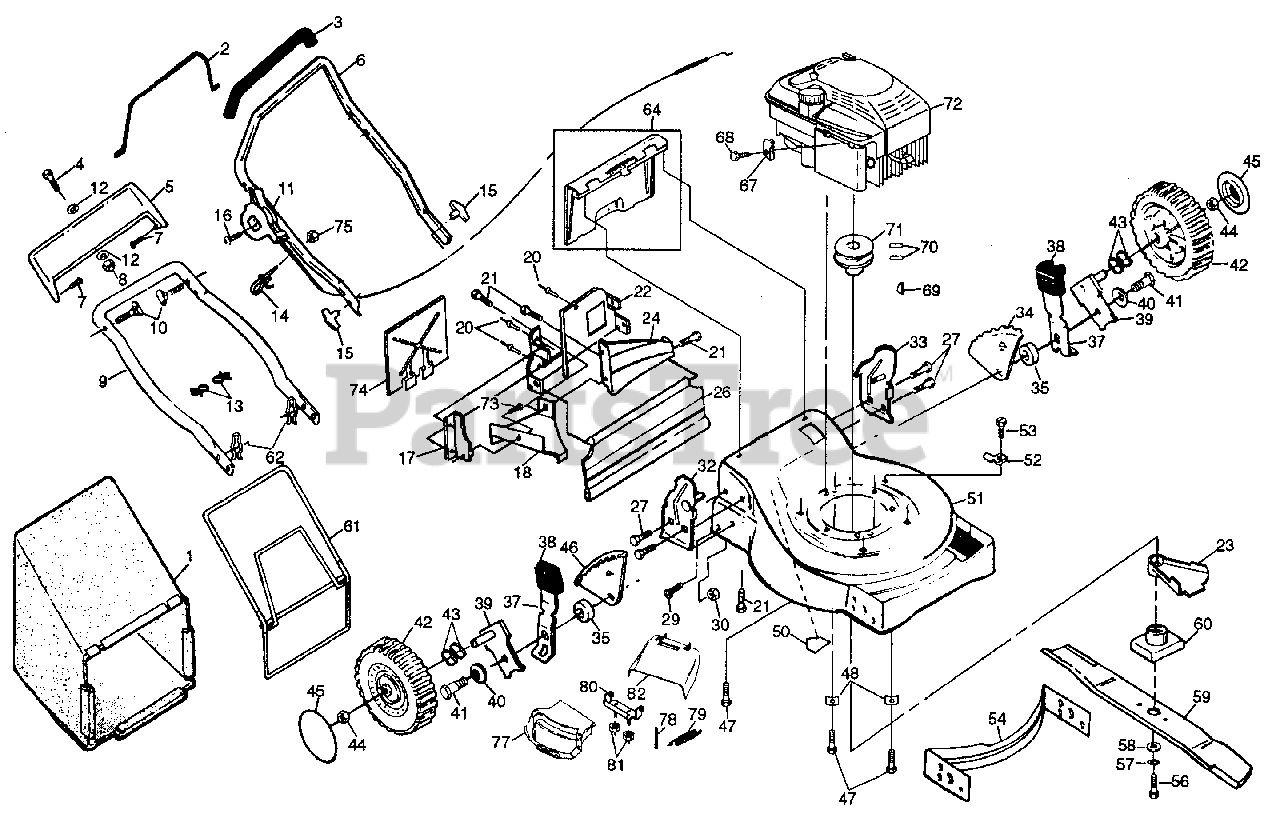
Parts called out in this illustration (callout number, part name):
1	Grass Bag Assembly
2	Control Bar
3	Handle Grip
4	Hex Washer Head Machine Screw 1/4-20 x 1-1/2
5	Trim Plate
6	Upper Handle
7	Self-tapping Screw #10-24 x 5/8
8	Locknut 1/4-20
9	Lower Handle
10	Handle Bolt
11	Throttle Control
13	Caple Clips
14	Rope Guide
15	Handle Knob
16	Round Head Screw 1/4-20 x 2-3/4
17	Side Baffle
18	Discharge Baffle
21	Hex Tapping Screw 1/4-20 x 1/2
22	Back Plate
23	Debris Shield
24	Rear Baffle
26	Rear Skirt
27	Thread Cutting Screw 5/16-18 x 3/4
29	Hinge Screw
30	LOCKnut
32	Handle Bracket Assembly (Right)
33	Handle Bracket Assembly (Left)
34	Wheel Adjusting Bracket (LR)
35	Spacer
37	Selector Spring
38	Selector Knob
39	Axle, Arm Assembly
40	Bellville Washer
41	Shoulder Bolt 3/8-16
42	Wheel & Tire Assembly
43	Wave Washer
44	Nut
46	Wheel Adjusting Bracket (RR)
47	Thread Rolling Screw 3/8-16 x 1
48	Engine Washer
50	Danger Decal
51	Lawn Mower Housing
52	Guide Clip (Housing)
53	Hex Washer Head Screw #10-24 x 1/2
54	Front Baffle
56	Hex Head Screw 3/8-24 x 1-3/8 Gr. 8
57	Helical Lockwasher 3/8
58	Hardened Washer
60	Blade Adapter
61	Catcher Frame Assembly
62	Hairpin Cotter
64	Rear Door Assembly
67	Cable Clamp
68	Thread Rolling Screw #10-32 x 5/8
69	Hi-Pro Key
70	Set Screw 1/4-20 x 5/16
71	Engine Pulley
74	Mulcher Plate
75	Keps Locknut
77	Mulcher Door
79	Hinge Spring
80	Hinge Bracket
81	Nut
82	Clip-on Discharge Guard
